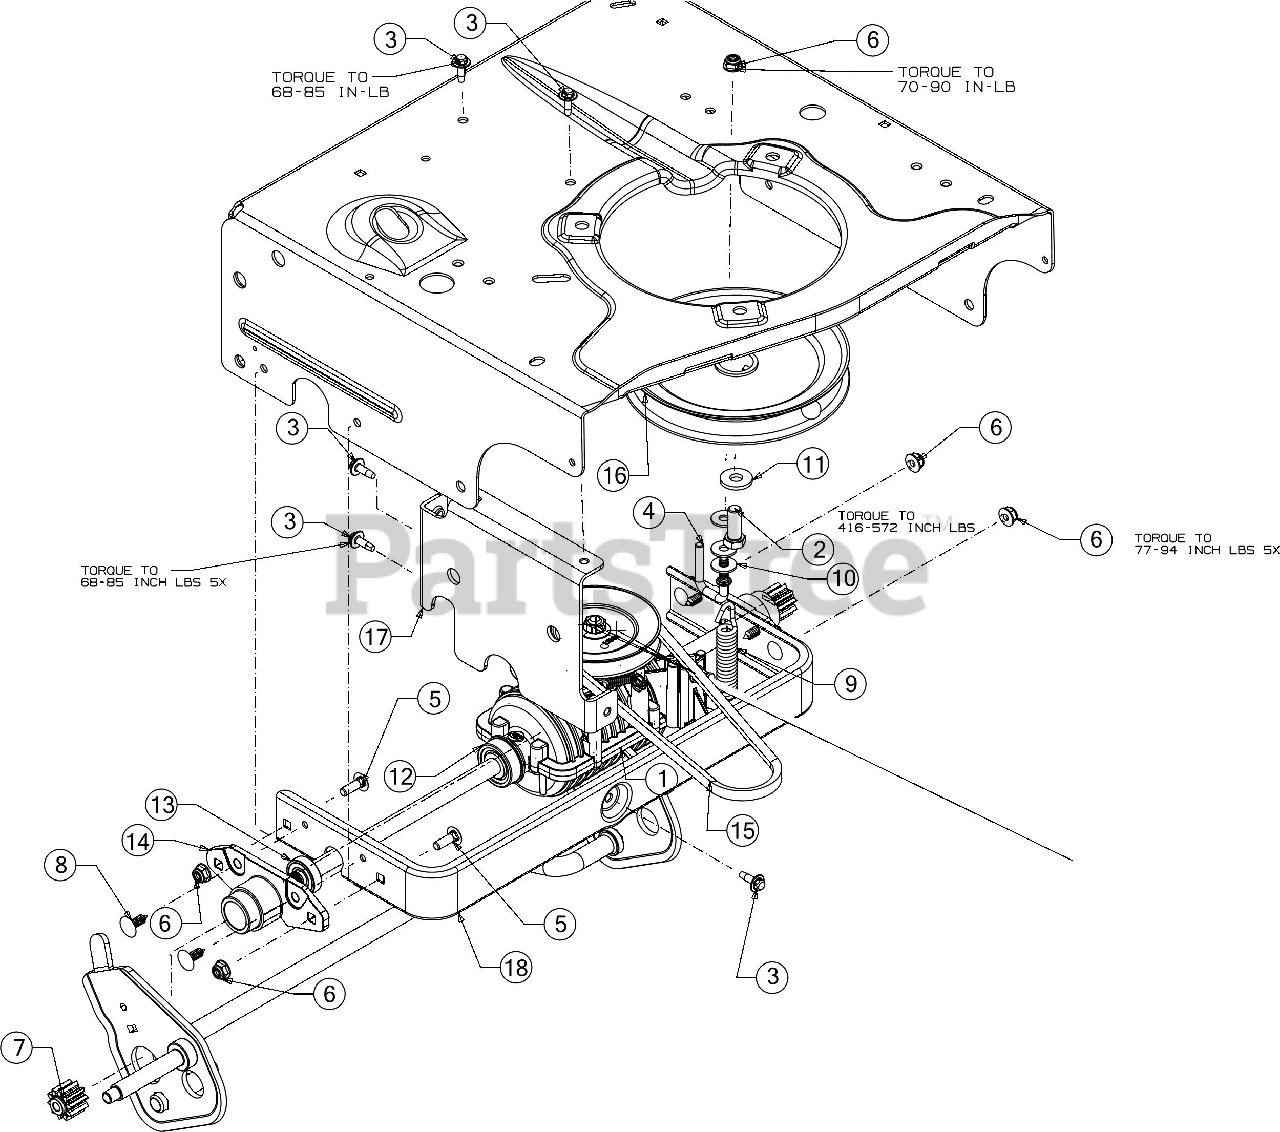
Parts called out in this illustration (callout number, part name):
1	TRANSMISSION
2	SCREW 3/8-24 x 1.00 GR5
3	SCREW M6-1 x .625
4	SPRING GUIDE EYE BOLT-1/4 x 20
5	SCREW 1/4-20 x .75 GR5
6	FLANGE LOCK NUT
7	SPUR GEAR 10T
8	RATCHET CLIP .250
9	EXTENSION SPRING
10	FLAT WASHER .28 ID x .74 OD x .063
11	WASHER
12	ROLLER BEARING
13	BALL BEARING
14	DRIVE BEARING
15	BELT 3/8 x 24.68"
16	ENGINE PULLEY
